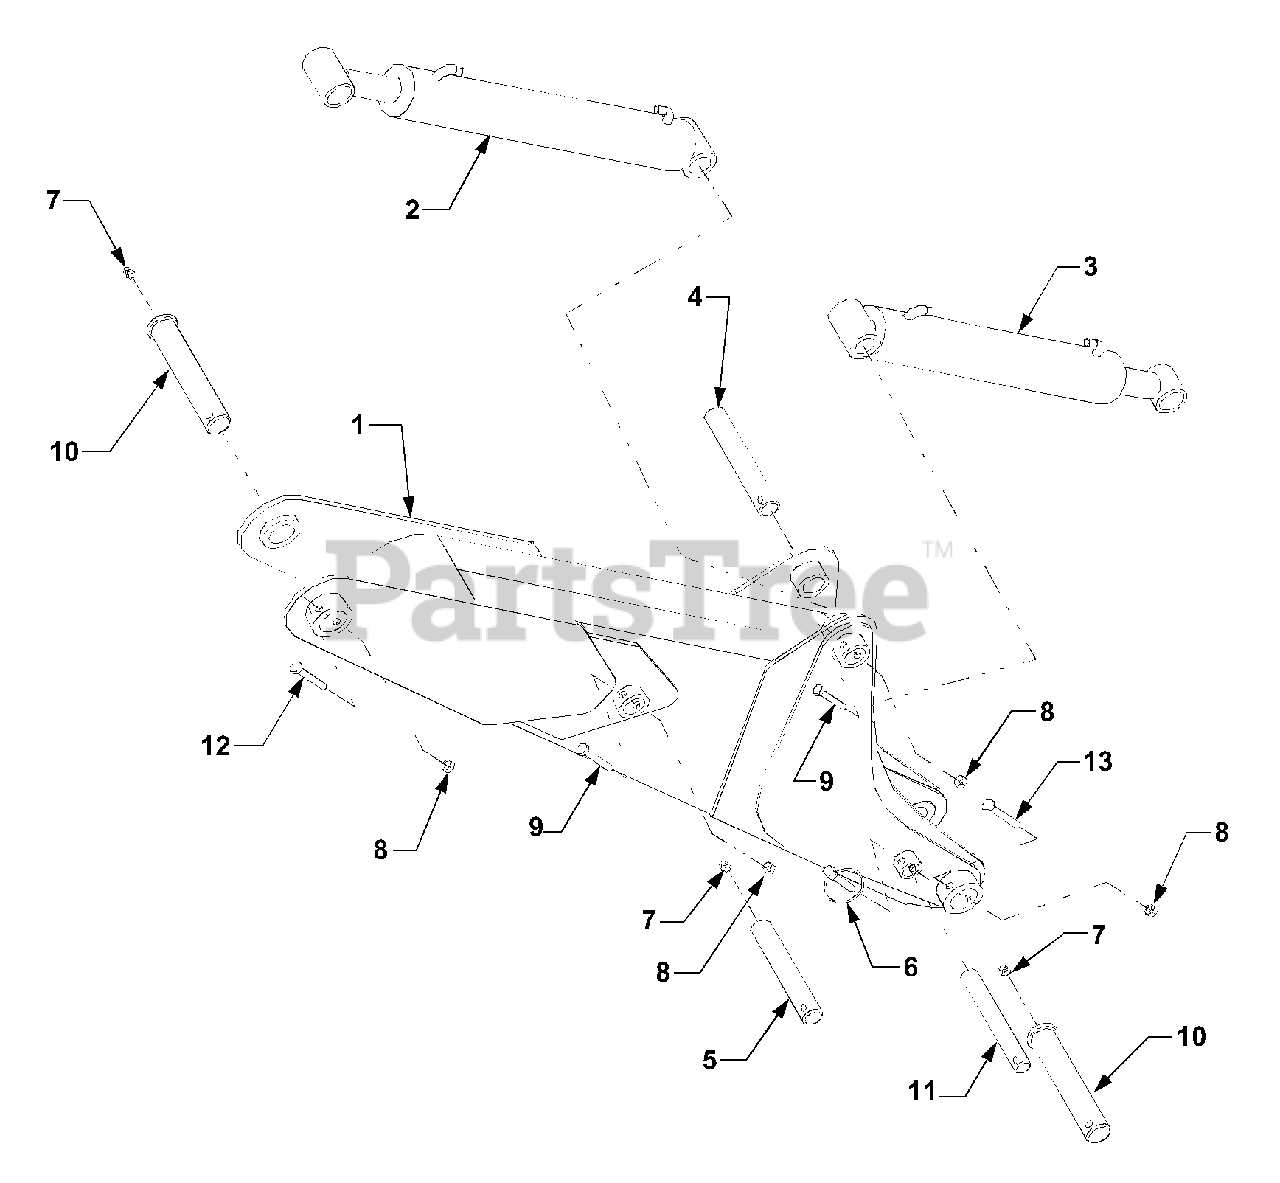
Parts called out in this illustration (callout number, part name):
2	Cylinder Ass'y. - Dipperstick
3	Cylinder Ass'y. - Boom
7	Grease Nipple
8	Hex Nut, M10 Lock
9	Hex Head Screw, M10 x 50
12	Hex Head Screw, M10 x 60
